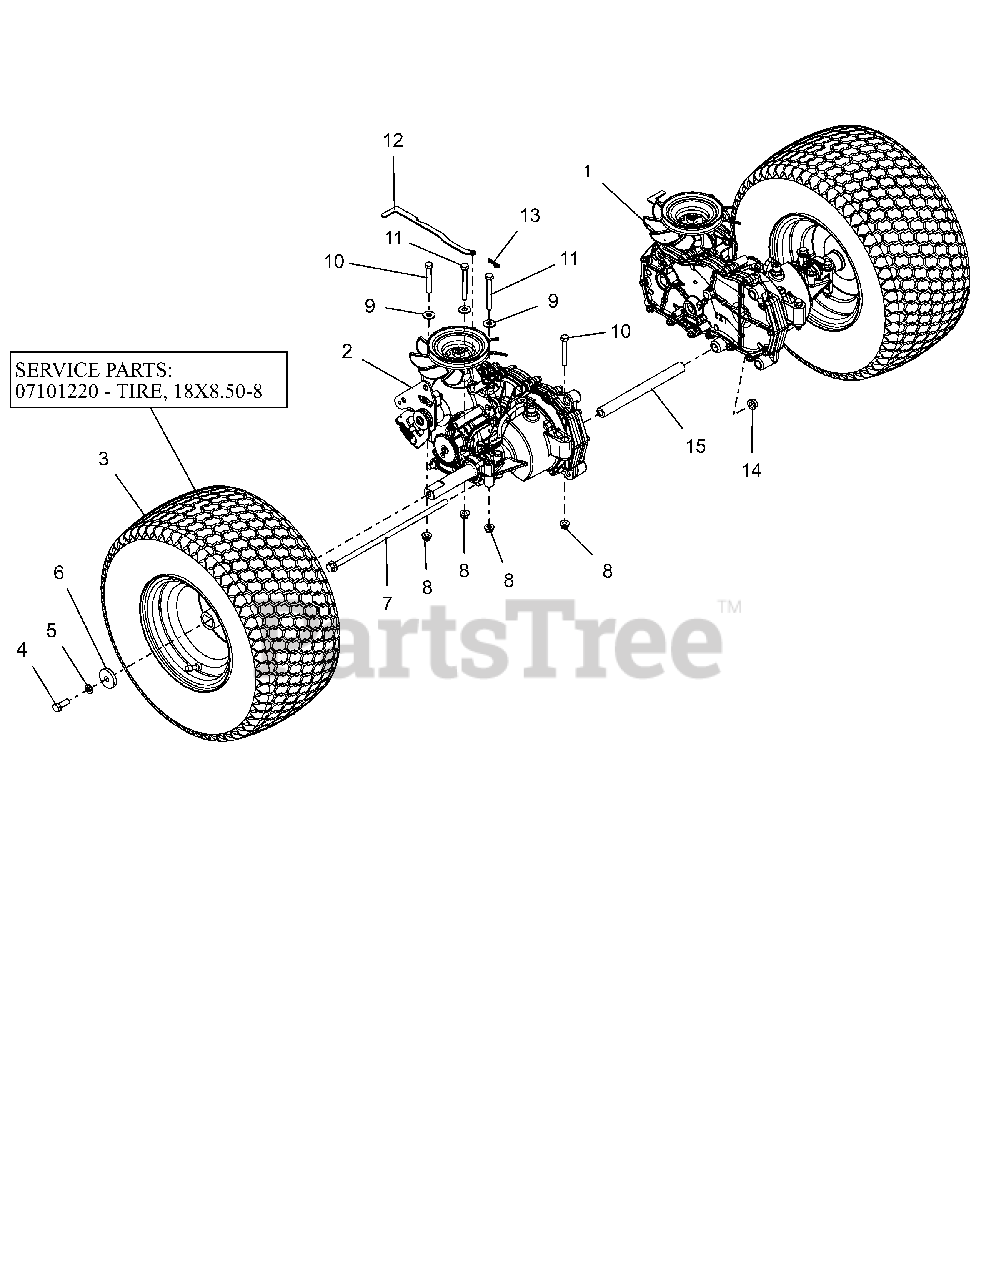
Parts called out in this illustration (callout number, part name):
1	TRANSAXLE, LH EZT D-SHFT SHORT
2	TRANSAXLE, RH EZT D-SHFT SHORT
3	ASM, WHL/TIRE 18X8.50-8 DHUB
3	TIRE, 18X8.50-8
4	BLT, HEX .38-16X1.00 G8ZCCEP30
5	WSHR,LK-REG .375X.094 ZCC
6	WSHR, FLT .406X1.50X.245 ZCC
7	BLT, HEX-FLG 0.375-16X11.5 GR5 ZC120
8	NUT,NYL-FLG .31-18 GF ZCC
9	WSHR,FLT .375X.875X.083 ZCC
10	BLT, HEX .31-18X2.25 G5 ZCC
11	BLT, HEX .31-18X2.75 G5 ZCC
12	BRKT, DUMP VALVE
13	PIN, HAIR #213 .08X1.19 ZCC
14	NUT-LK-CTR-FLG .375-16 GF ZCC
15	SPCR, TRANSAXLE .438 ID X .750 OD X 8.18 (BLACK)
